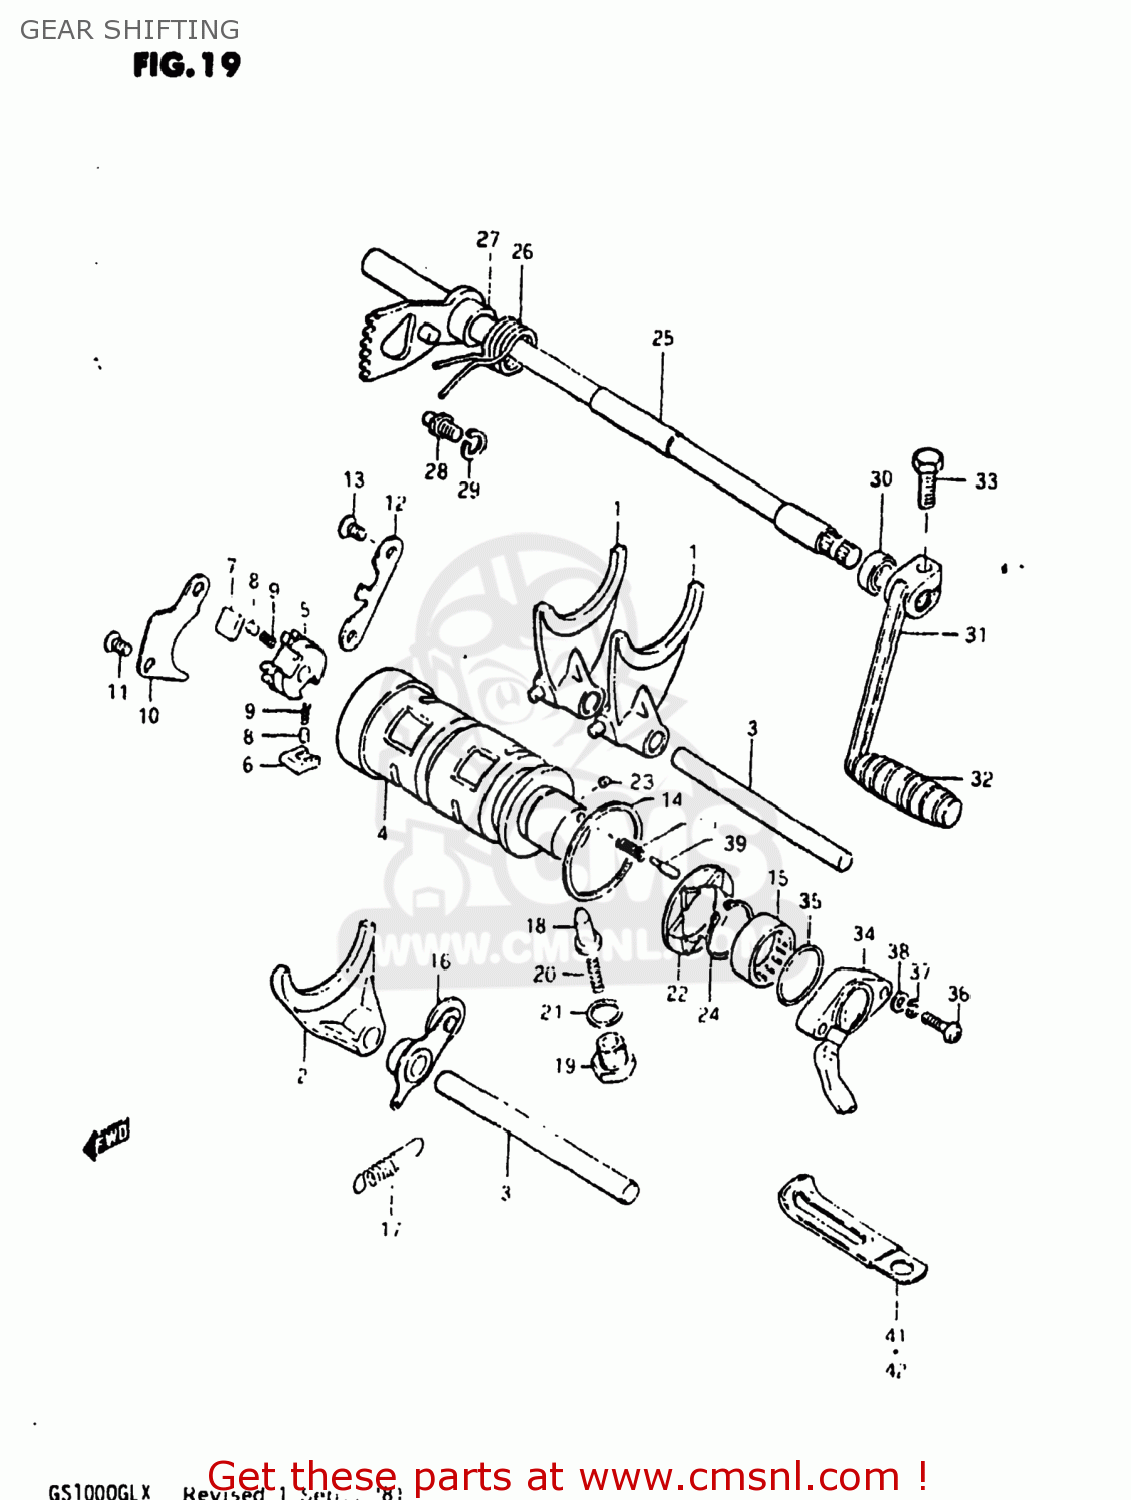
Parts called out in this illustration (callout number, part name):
1	FORK,GEAR SHIFT NO.1
2	FORK,GEAR SHIFT NO.3
3	SHAFT,GEAR SHIFT FORK
4	CAM,GEAR SHIFT
5	SHIFTER,GEAR SHIFT CAM
6	PAWL,GEAR SHIFT NO.1
7	PAWL,GEAR SHIFT NO.2
8	PIN(5X8)
9	SPRING
10	LIFTER,GEAR SHIFT PAWL
11	SCREW
12	GUIDE,GEAR SHIFT CAM
13	SCREW
14	WASHER(40X45X1)
15	BEARING
16	STOPPER,GEAR SHIFTING
17	SPRING
18	STOPPER,GEAR SHIFT CAM NO.2
19	HOLDER,GEAR SHIFT CAM STOP SPR
20	SPRING
21	GASKET(14X19.2X2) (NAS)
22	PLATE,GEAR SHIFT CAM STOPPER
23	PIN 4X6
24	CIRCLIP
25	SHAFT,GEAR SHIFT
26	SPRING
27	SPACER (12X20X12)
28	STOPPER,GEAR SHIFT CAM
29	WASHER
30	OIL SEAL
31	LEVER ASSEMBLY,GEAR SHIFTING
32	RUBBER,GEAR SHIFT PEDAL
33	BOLT
34	TERMINAL BASE ASSY,GEAR SHIFT
35	O-RING (D:2.4 ID:26.2)
36	SCREW 5X20
37	LOCK WASHER
38	WASHER
39	PIN(5X15.5)
40	SPRING
41	CLAMP L:35
42	CLAMP
